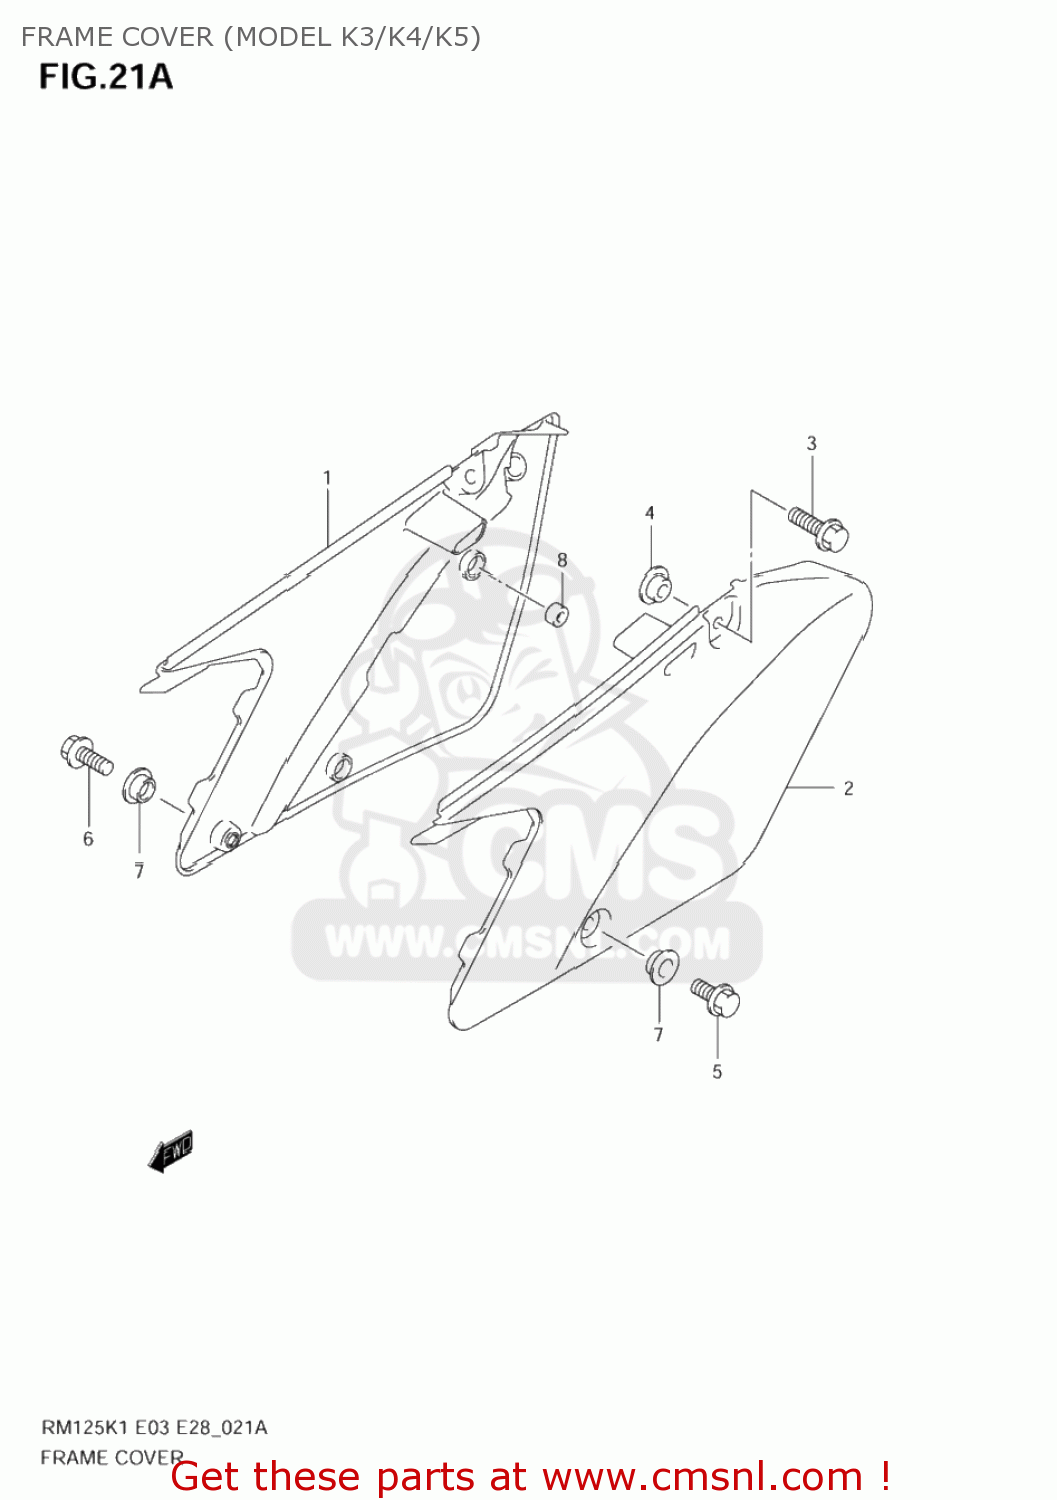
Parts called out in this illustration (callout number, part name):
1	COVER,FRAME R
2	COVER,FRAME,L
3	BOLT
4	WASHER,FRAME C
5	BOLT(6X12)
6	BOLT(6X16)
7	WASHER
8	CUSHION,FRAME COVER,R
